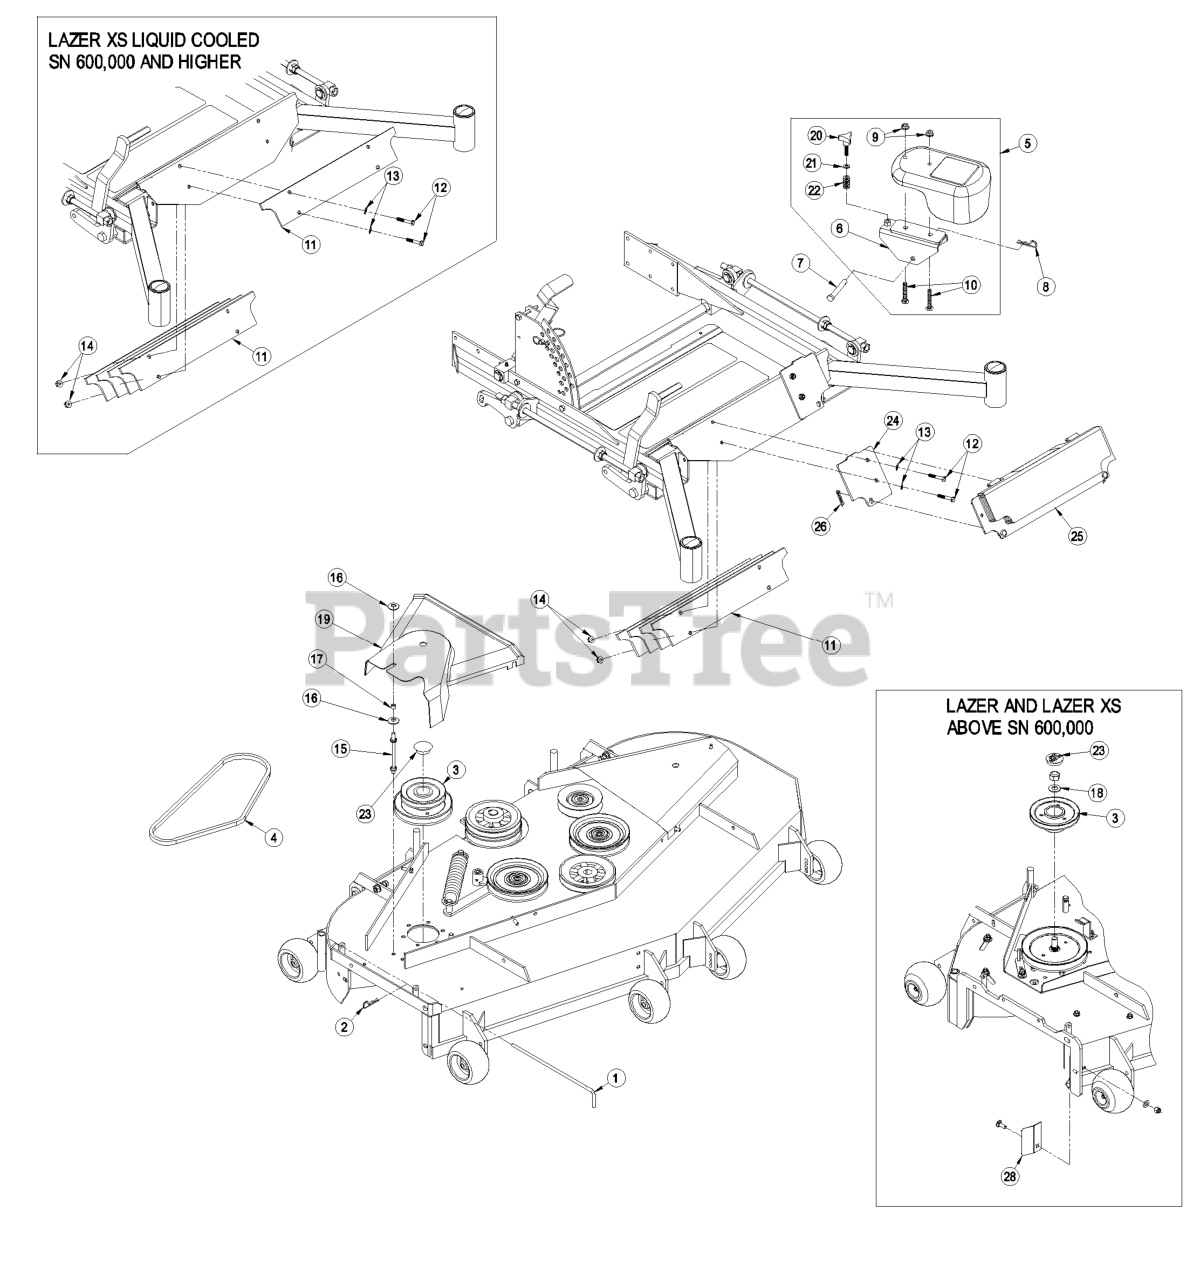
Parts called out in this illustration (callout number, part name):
1	PIN,CHUTE PIVOT
2	PIN-COTTER
3	JACKSHAFT, LZUV60
4	BELT, BLOWER DRIVE 60
5	ASM, WEIGHT 1.5" 70 POUND
6	WLD, BRACKET 2.0 ARM
7	PIN-CLEVIS
8	PIN-COTTER
9	NUT-HHF, WHIZ
10	BOLT, SQUARE HEAD YZ
11	PLATE, WEIGHT
12	SCREW-HH
13	WASHER-PLAIN
15	STUD,BELT SHIELD 4 INCH
16	WASHER-SPRING
18	Washer, 5/8 SAE
19	COVER, BELT 60
21	WASHER-FLAT
23	PLUG, BLACK NYLON 1.75
24	PLATE, WEIGHT MOUNTING
25	ASM, WEIGHT PLATE WITH DE
26	PIN-HAIR
28	Deflector
